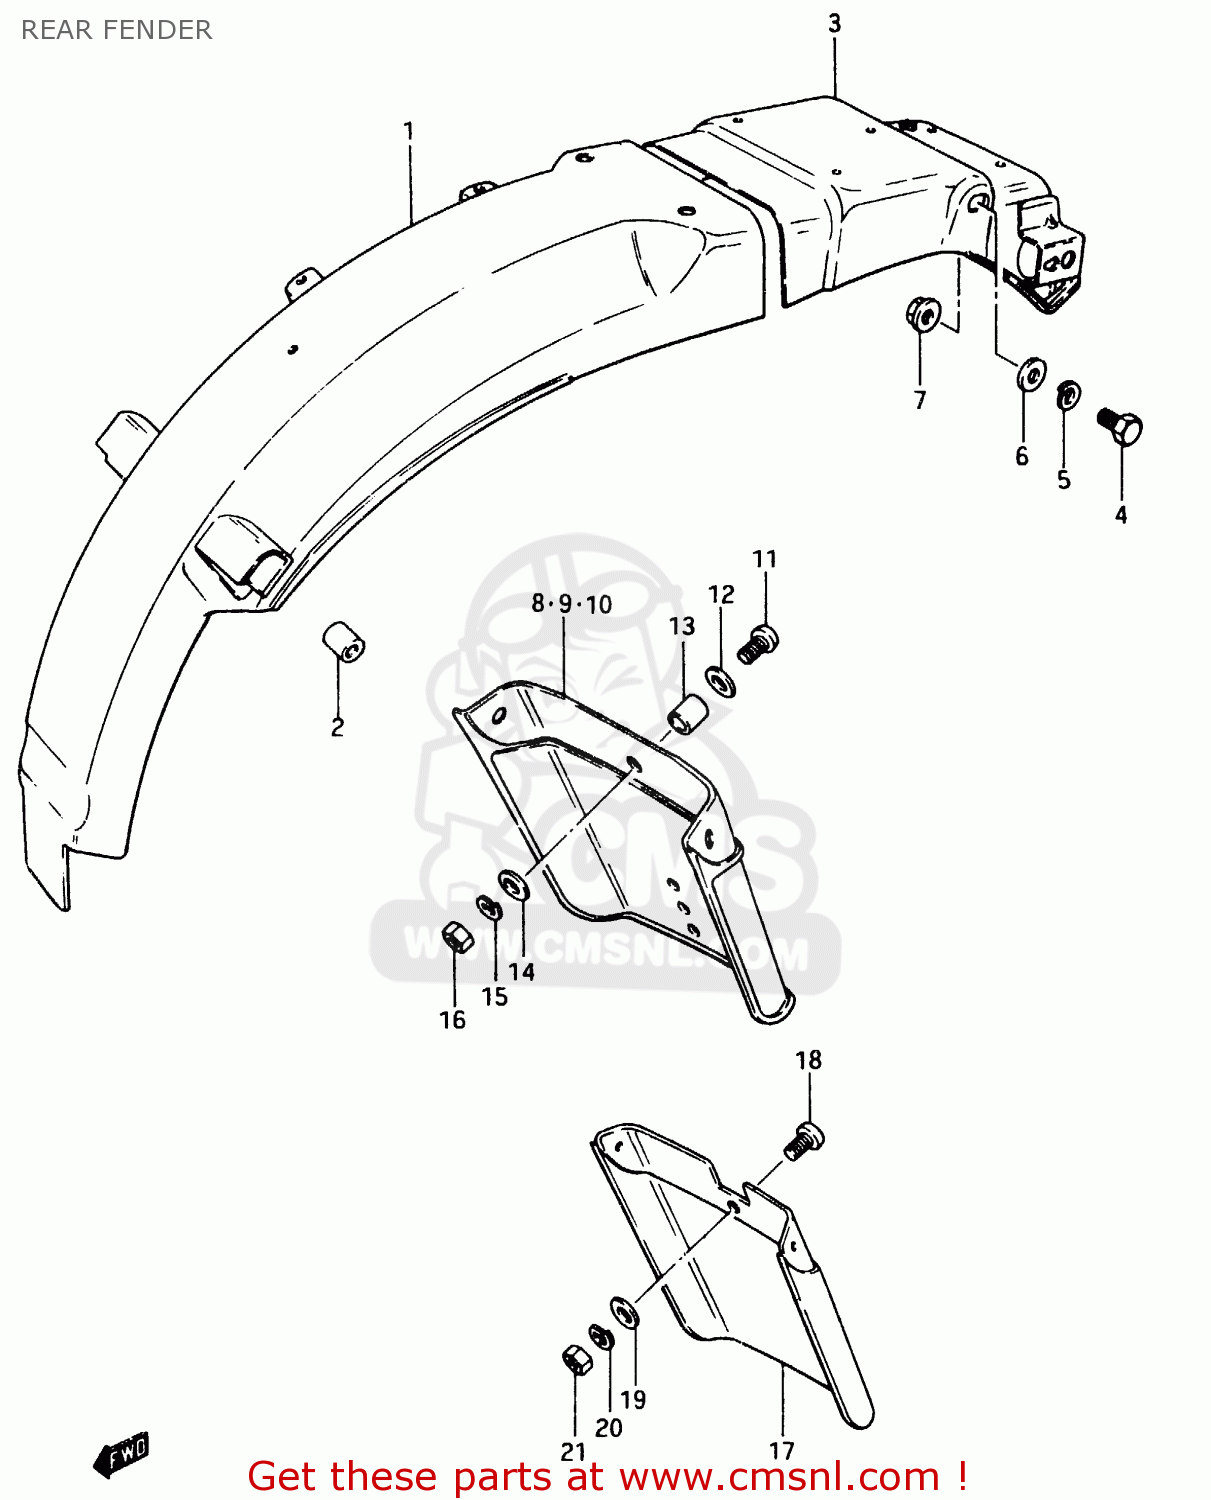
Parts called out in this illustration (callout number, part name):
1	BODY,REAR FENDER,FRONT
2	CUSHION
3	REINFORCEMENT,RR FENDER
4	BOLT,8X1.25X2
5	WASHER,LOCK,8.
6	WASHER 8MM
7	NUT, WHEEL SET
8	EXTENSION, REAR
9	EXTENSION,RR F
10	EXTENSION, REAR
11	SCREW
12	WASHER
13	SPACER(6.2X8.3X5.7)
14	WASHER
15	LOCK WASHER
16	NUT 6MM
17	MUD GUARD
18	SCREW
19	WASHER
20	LOCK WASHER
21	NUT
